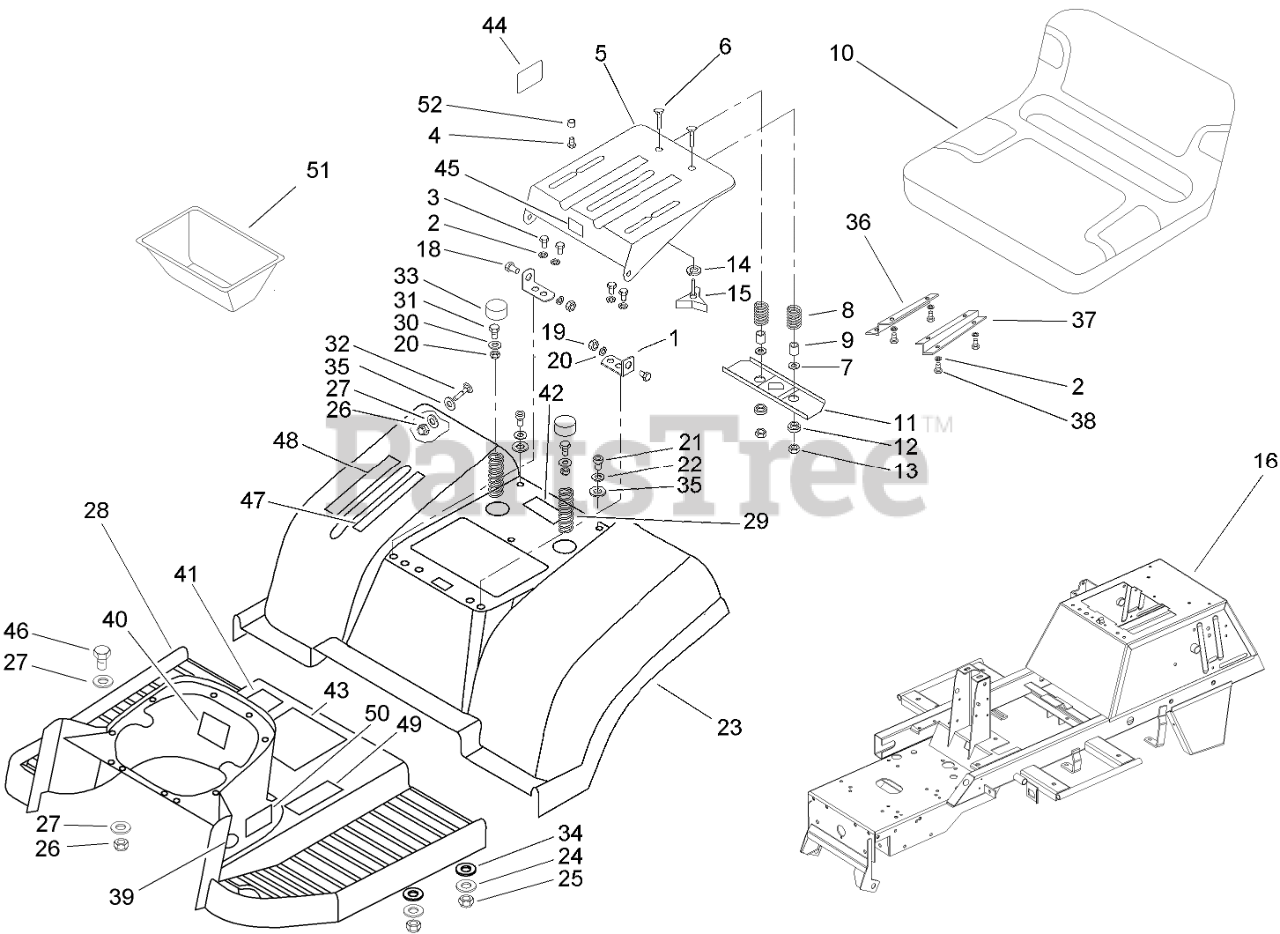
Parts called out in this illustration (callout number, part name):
1	BRACKET-SUPPORT, SEAT
2	WASHER-LOCK, SPRING
3	SCREW-HH
4	SCREW-HH
5	SUPPORT-SEAT
6	BOLT-CARRIAGE
7	WASHER-FLAT
8	SPRING-SEAT
9	SPACER-SPLIT
10	SEAT ASM
11	BRACKET
12	BUSHING
13	NUT-LOCK
14	WASHER-SPRING
15	KNOB-ADJUSTMENT
16	CHASSIS-FRAME
18	SCREW-SUPPORT, SEAT
19	WASHER-PLAIN
20	NUT-LOCK, NI
21	SCREW-HSFH
22	WASHER-FINISH
23	Fender
24	WASHER-FLAT
25	NUT-LOCK, NI
26	NUT-LOCK
27	WASHER-FLAT
28	FOOTREST ASM
29	SPRING-SEAT
30	WASHER-PLAIN
31	SCREW-HH
32	BOLT-CARRIAGE
33	CAP-HUB
34	WASHER-RUBBER
35	WASHER-RUBBER
36	BRACKET-SEAT, RH
37	BRACKET-SEAT, LH
38	Screw
39	DECAL-BRAKE, PARKING
40	DECAL-STARTING
41	DECAL-OPERATION, HYDRO
42	DECAL-BAG TO FRAME
43	DECAL-INSTRUCTION
44	DECAL-SWITCH
45	DECAL-DANGER
46	SCREW-HH
47	DECAL-HOC, LH
48	DECAL-HOC, RH
49	DECAL-OPERATION
50	DECAL-TOWER
51	Box-Battery
52	SHIM-SEAT
